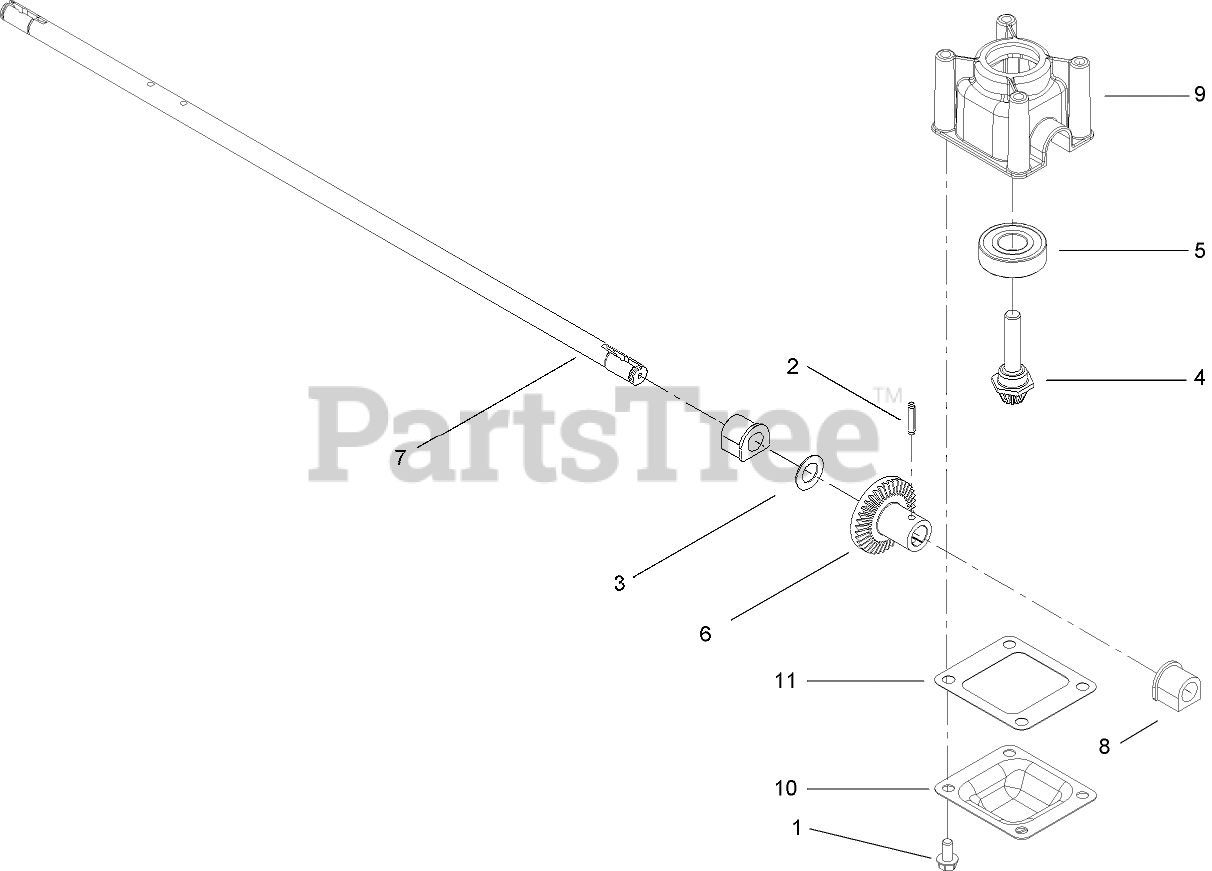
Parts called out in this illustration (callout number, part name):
1	SCREW-HWH
2	PIN-GROOVE
3	WASHER-PLAIN
4	PINION
5	BEARING-BALL
6	Gear-Bevel, 37t
7	Shaft-Output
8	Bushing-Shaft, Output
9	Gearcase-Upper
10	Cover-Gearcase
11	Gasket-Gearcase
